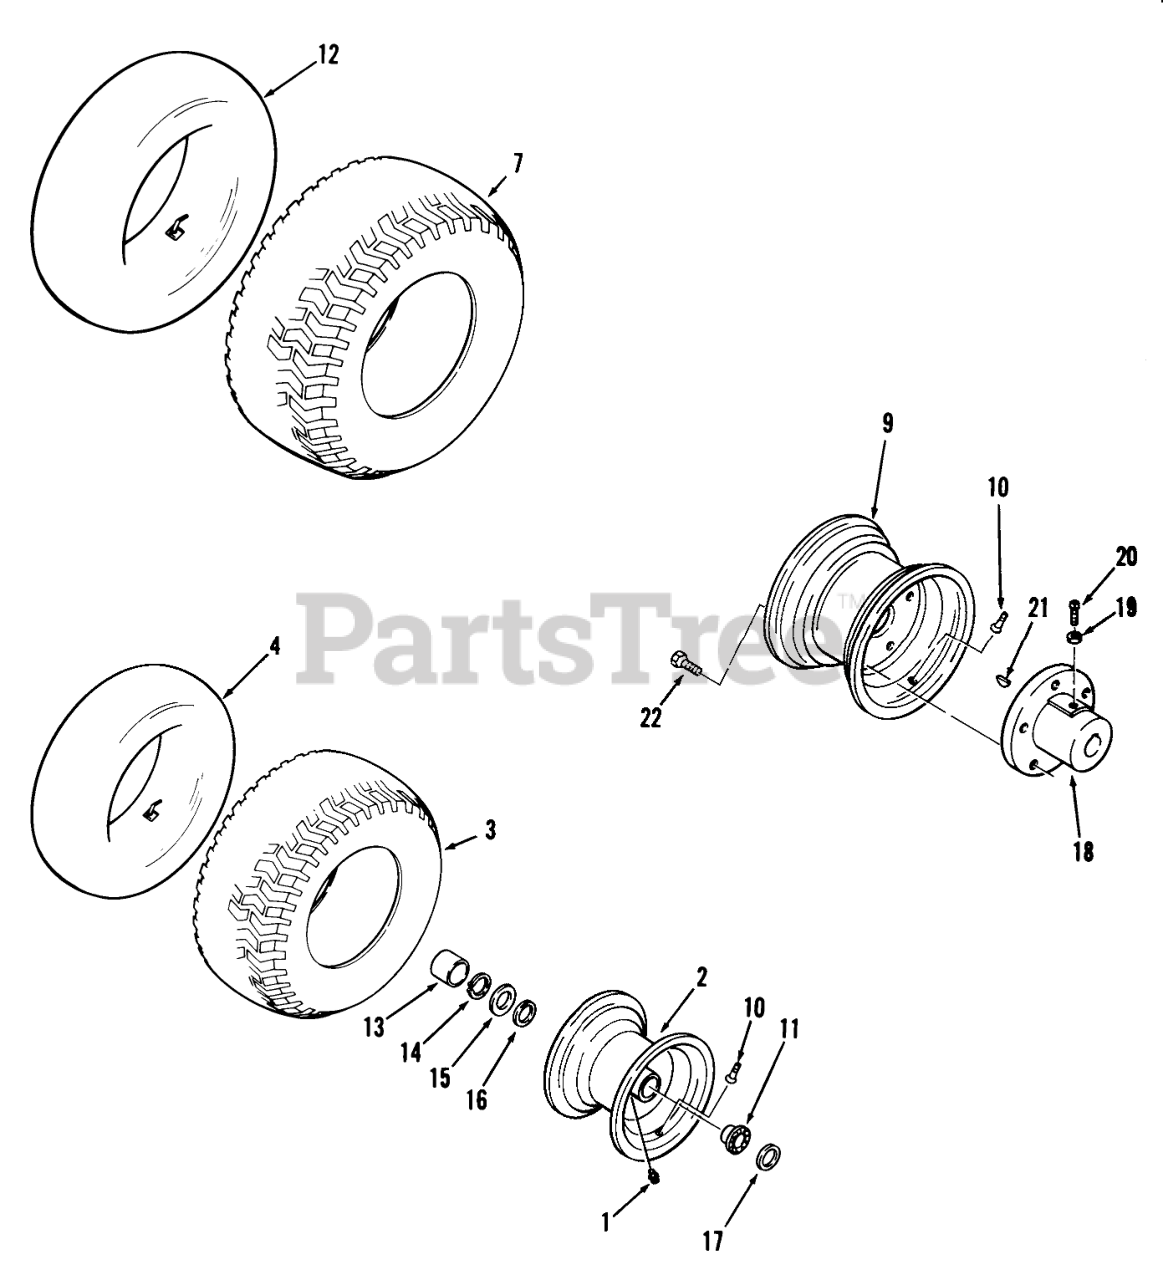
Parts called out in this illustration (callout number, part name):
1	Zerk
2	WHEEL
3	Front Tire 16 x 6.50-8
4	TUBE-INNER
7	TIRE 22 X 7.50-12
9	Wheel
10	VALVE
11	Bearing
12	INNER TUBE
13	HUB CAP
14	Snap Ring
15	Washer
16	WASHER
17	WASHER-SHIM
18	Hub-Rear
19	Nut
20	Screw-Set
21	WOODRUFF KEY
22	Lug Nut
